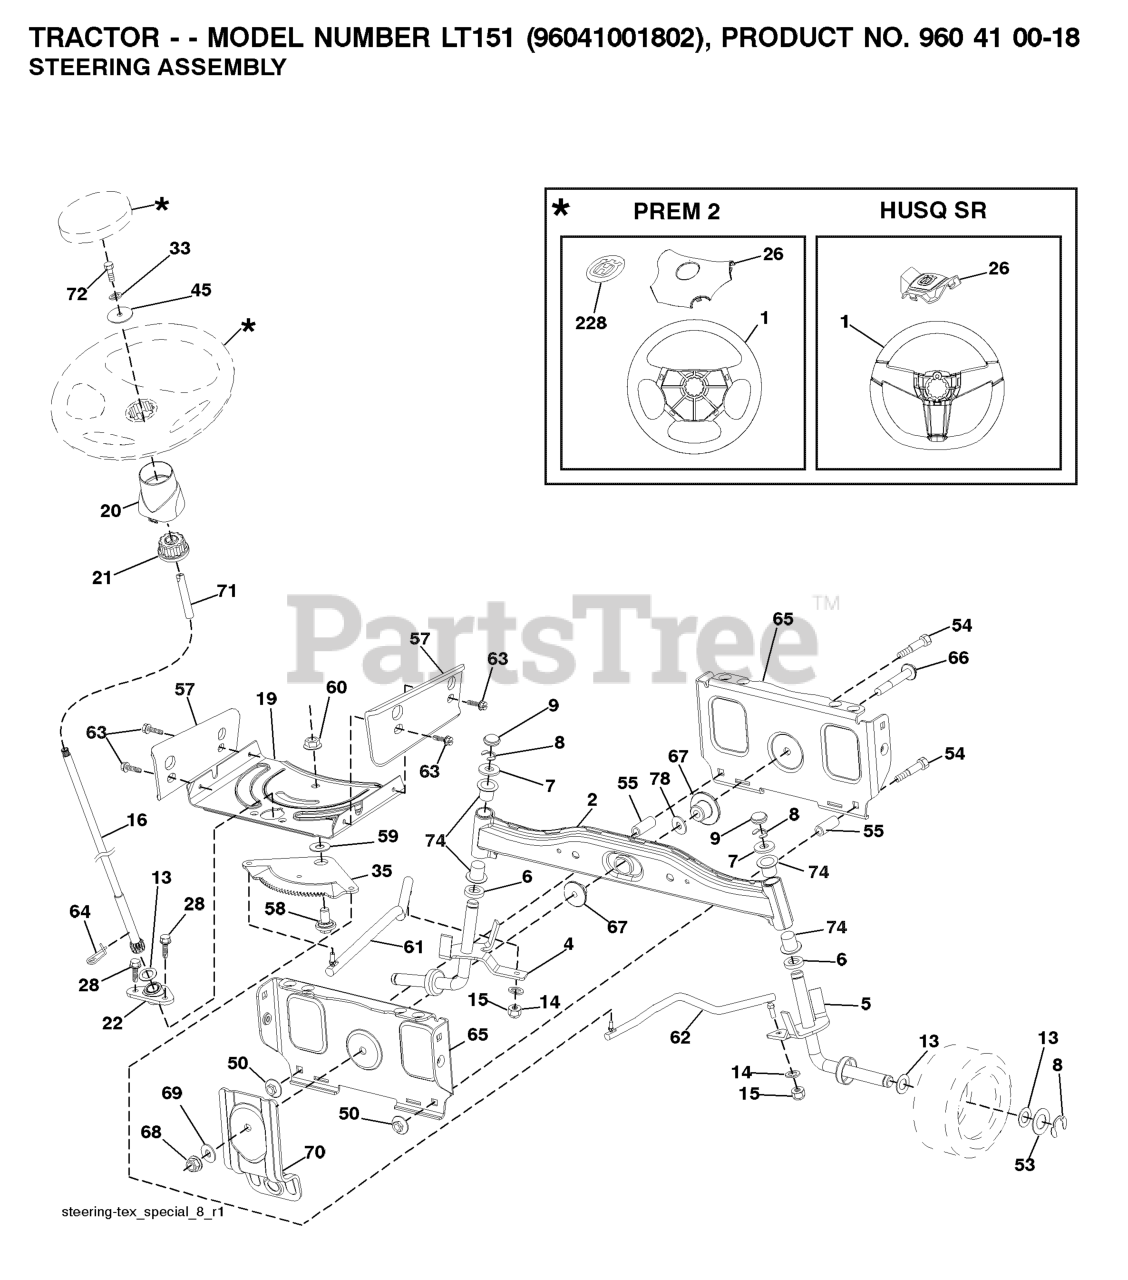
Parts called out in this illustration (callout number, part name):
1	RP WHEEL.STEER.HUSQ.PREM.OVMLD
2	AXLE.HALF.ASM.WELDED
4	SPINDLE.WELDED.LH.15"TEX
5	SPINDLE.WELDED.RH.15"T
6	THRUST WASHER
9	CAP.SPINDLE.BLACK
14	WASHER, LOCK 3/8
15	NUT CROWNLOCK 3/8-24
16	SHAFT STEERING
19	PLATE.STEER.DDL.NLT/NG
20	BOOT, STEERING
21	ADAPTER, WHEEL STNG..
22	BUSHING.ASM.STEERING.A
26	RP INSERT.CAP.WHL.STRG.HUSQ.
28	SCREW, 3/8-16X3/4
33	WASHER.LOCK.HVY.HLCL.SPR.5/16
35	GEAR.SECTOR.PLATE.DDL.
45	WASHER.11/32
50	NUT LOCK FLG 3/8-16 UNC
53	WASHER.HARDENED
55	SPACER.BRACE.AXLE (2 2)
57	BRACKET.UPSTOP.TEX
58	BOLT.SHOULDER.SECTOR.P
59	WASHER.THURST.SECTOR.S
60	NUT FLANGE LOCK 5/8-11
61	DRAGLINK.LH.BALLSTUD.D
62	DRAGLINK.RH.BALLSTUD.D
63	SCREW
64	RETAINER.CLIP.SPRING.S
65	BRACE.AXLE.FRONT.NLT/N
66	BOLT HEX FGHD 7/16-14 X 3 SERR
67	BUSHING.PM.FRONT AXLE
68	NUT.LOCK.FLANGE.7/16
69	WASHER.1.5X.505X.118
70	BRKT.DECK.SUSPENSION.F
71	SHAFT EXTENSION STEERING
72	BOLT YT
74	BRNG T
78	THRUST WASHER
228	DECAL.WHEEL.STRG.LGN.H
